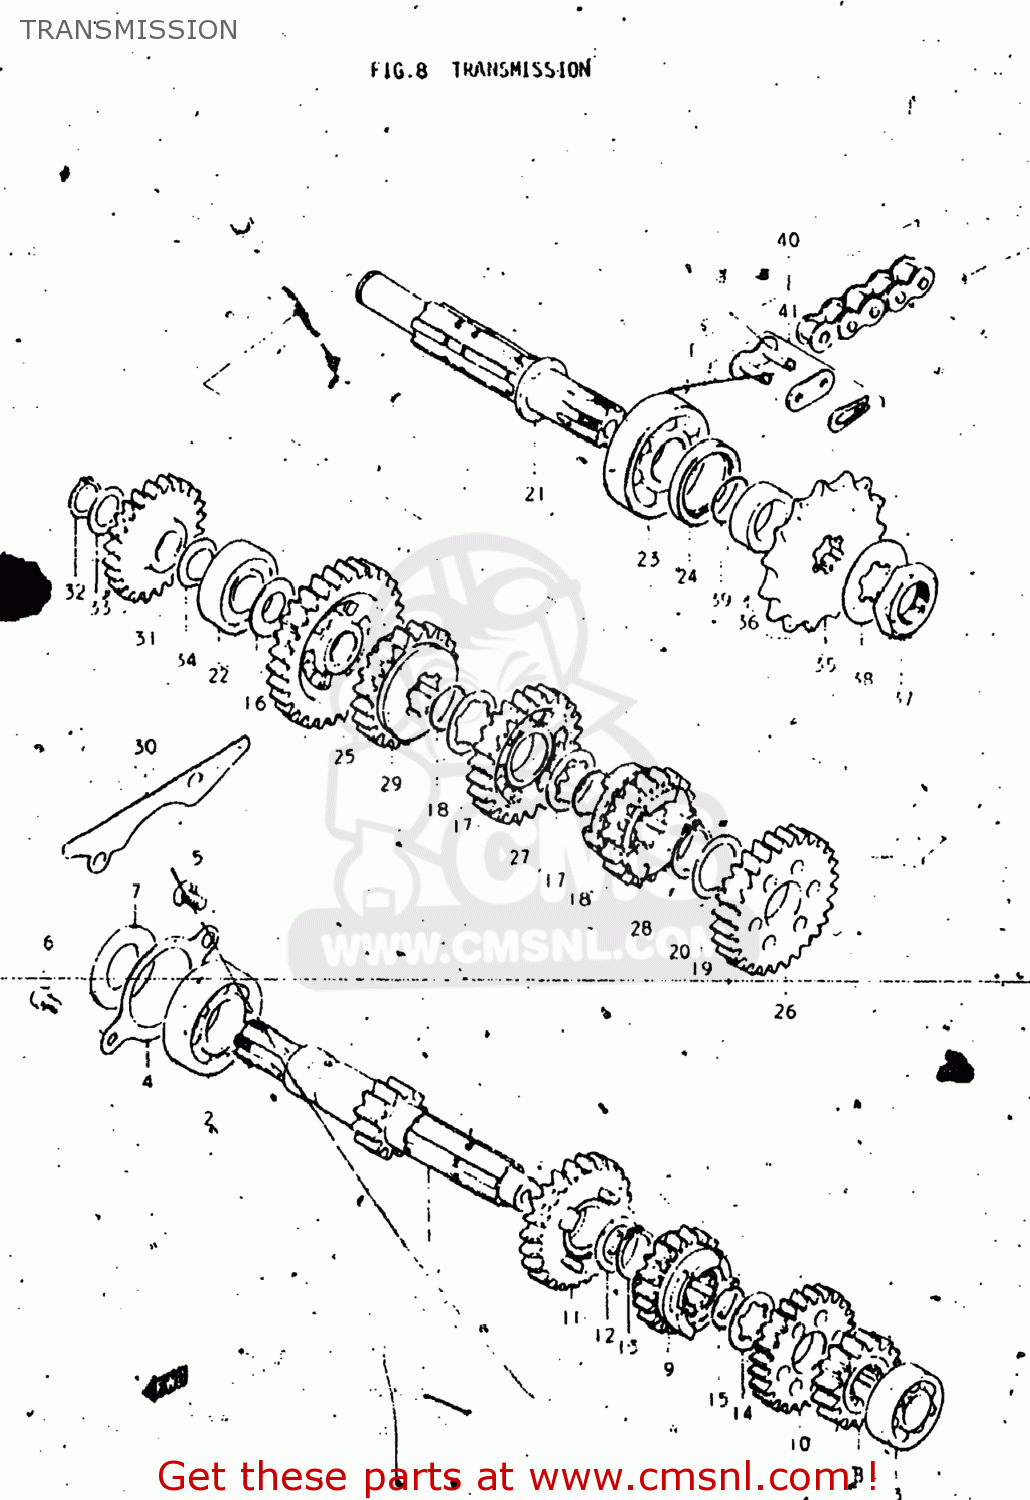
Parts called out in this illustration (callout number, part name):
1	SHAFT,COUNTER
2	BEARING
3	BEARING
4	PLATE,COUNTERSHAFT BEARING
5	SCREW
6	SCREW
7	WASHER(25X41X3)
8	GEAR,SECOND DRIVE
9	GEAR,FIFTH DRIVE
10	GEAR,FIFTH DRIVE
11	GEAR,FIFTH DRIVE
12	SHIM
13	CIRCLIP
14	WASHER,LOCK
15	CIRCLIP
16	WASHER
17	WASHER
18	RING,SNAP
19	WASHER
20	RING,SNAP
21	SHAFT,DRIVE
22	BEARING
23	BEARING
24	SEAL,OIL(32X42X6)
25	GEAR,FIRST DRIVEN
26	GEAR,SECOND DRIVEN
27	GEAR,THIRD DRIVEN
28	GEAR,5TH DRIVEN
29	GEAR,FIFTH DRIVEN
30	PLATE,OIL RESERVOIR
31	GEAR,KICK STARTER IDLE
32	CIRCLIP
33	WASHER
34	WASHER
35	SPROCKET,ENGINE
36	SPACER(22X32X11.5)
37	NUT
38	WASHER,LOCK
39	O RING(D:1.7,ID:22)
40	CHAIN ASSEMBLY,DRIVE
41	JOINT ASSEMBLY,CHAIN
